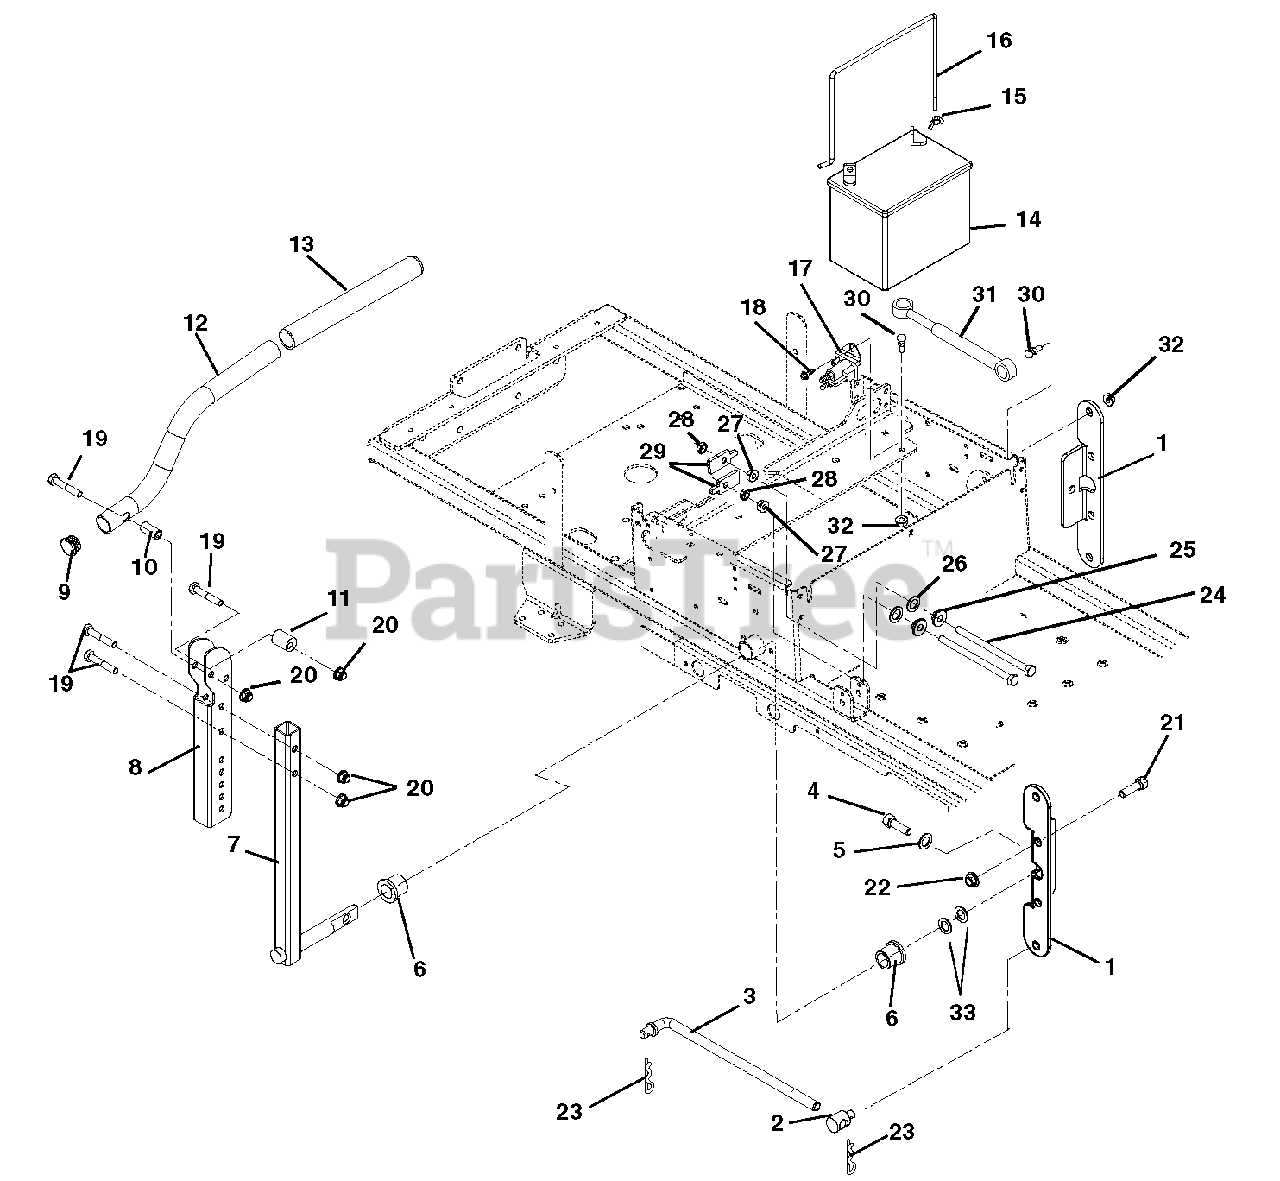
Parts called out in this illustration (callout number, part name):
1	Control Link
2	Pivot, Rod
3	Link, Wireform
4	Bolt, .38-16 x 1 Grade 8 EP30
5	Washer, Flat Steel .390 x 1.5 x .125
6	Bushing, 1.00 x .75 x 1.00
7	Weldment, Control Arm
8	Channel, Upper Handlebar
9	Caplug, Handlebar
11	Eccentric
12	Handlebar
13	Grip, Handlebar
15	Nut, Lock Wing .250-20
16	Battery Rod
17	Solenoid
18	Screw, Tap .250-20 x .37
19	Bolt, Hex .31-18 x 1.75 Grade 5
20	Nut, 5/16-18 Flange Nyloc
21	Bolt, Hex .38-16 x 1.25 Grade 5
22	Nut, Hex Jam .375-16
23	Pin, Hair Internal .08 x .18 x 1.18
24	Bolt, Hex 5/16-18 x 5 Grade 2
25	Bushing, Flange .312 x .500 x .344 x .880
26	Washer, Flat Steel .52 x .827 x .062
27	Nut, Spin Lock-Flange .312-18
28	Nut, Jam .312-18
29	Stop Tab
30	Stud, Ball
31	Damper, Control
32	Nut, Locking Top Flange .31-18
33	Washer, Flat Steel .755 x 1.25 x .125
